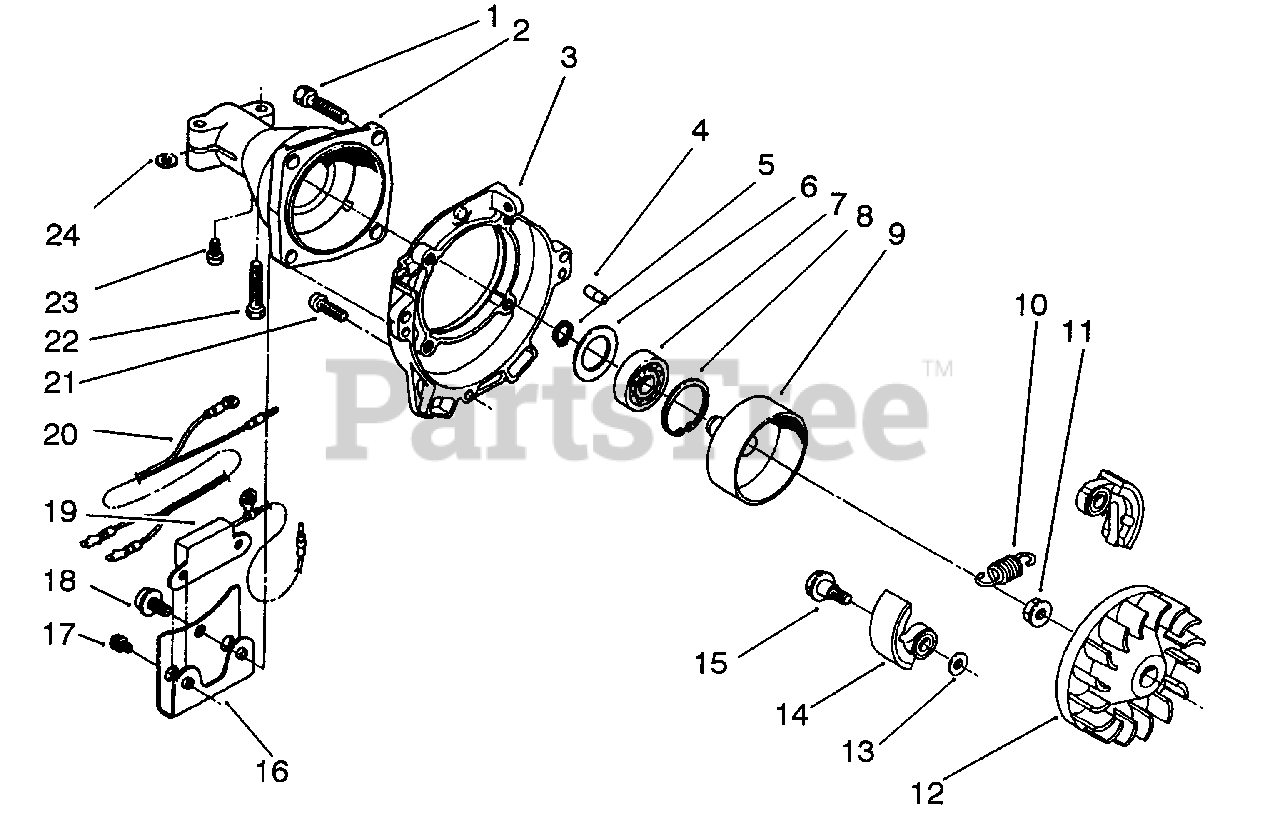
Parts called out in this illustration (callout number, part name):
1	Screw/Washer
2	Case-Clutch
3	Case-Fan
4	Pin-Dowel
5	Ring-Retaining
7	Bearing-Ball
8	Ring-Retainer
9	Drum-Clutch
14	Shoe-Clutch
15	Bolt-Clutch
16	Bracket-Unit
17	Screw/Washer
18	Screw/Washer
19	Transistor-Unit
21	Bolt/Washer
22	Bolt/washer
23	Screw/Washer
